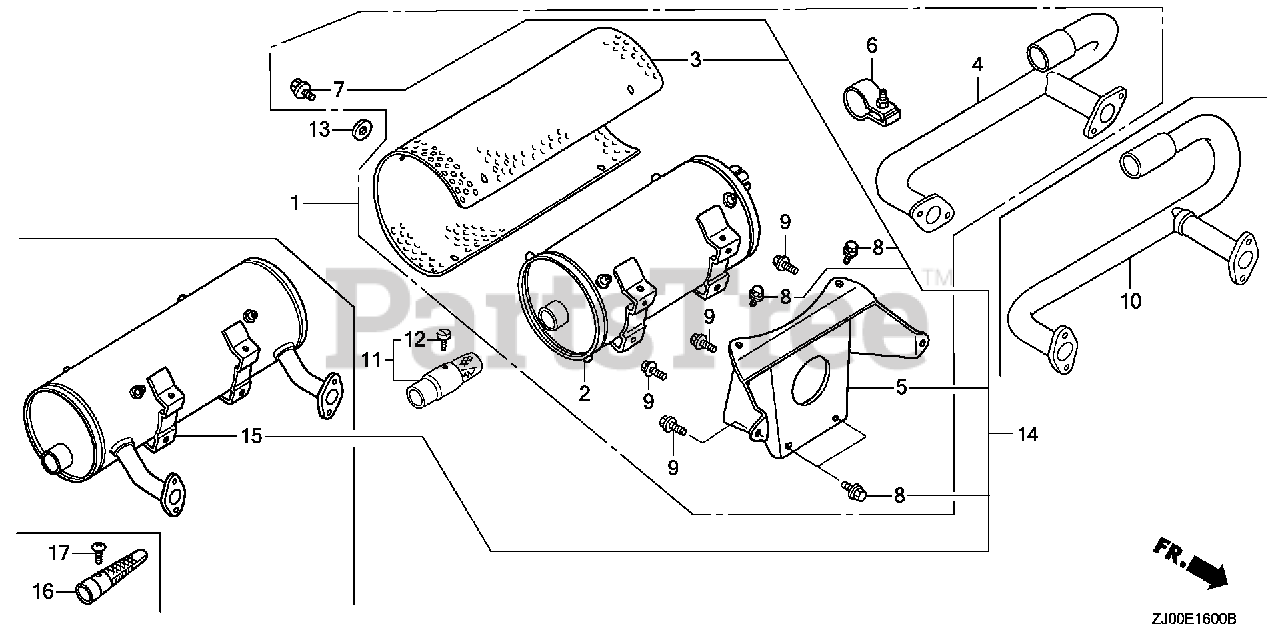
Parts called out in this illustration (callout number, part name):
1	MUFFLER KIT (HIGH-A) (N/A: SEE COMPONENTS)
2	MUFFLER COMP. (HIGH-R) (NELSON) (BLACK MUFFLER)
3	PROTECTOR, MUFFLER (HIGH) (FUTABA) (FOR BLACK MUFFLER)
4	PIPE, EX. (HIGH-R)
5	STAY, MUFFLER (HIGH-NELSON)
6	BAND ASSY. (FOR BLACK MUFFLER) (NOT AVAILABLE)
7	BOLT, FLANGE (6X8)
8	BOLT, FLANGE (8X14)
9	BOLT, FLANGE (8X20)
11	ARRESTER, SPARK (FOR BLACK MUFFLER)
12	SCREW (NELSON) (FOR BLACK MUFFLER)
13	WASHER, SPRING (6MM)
